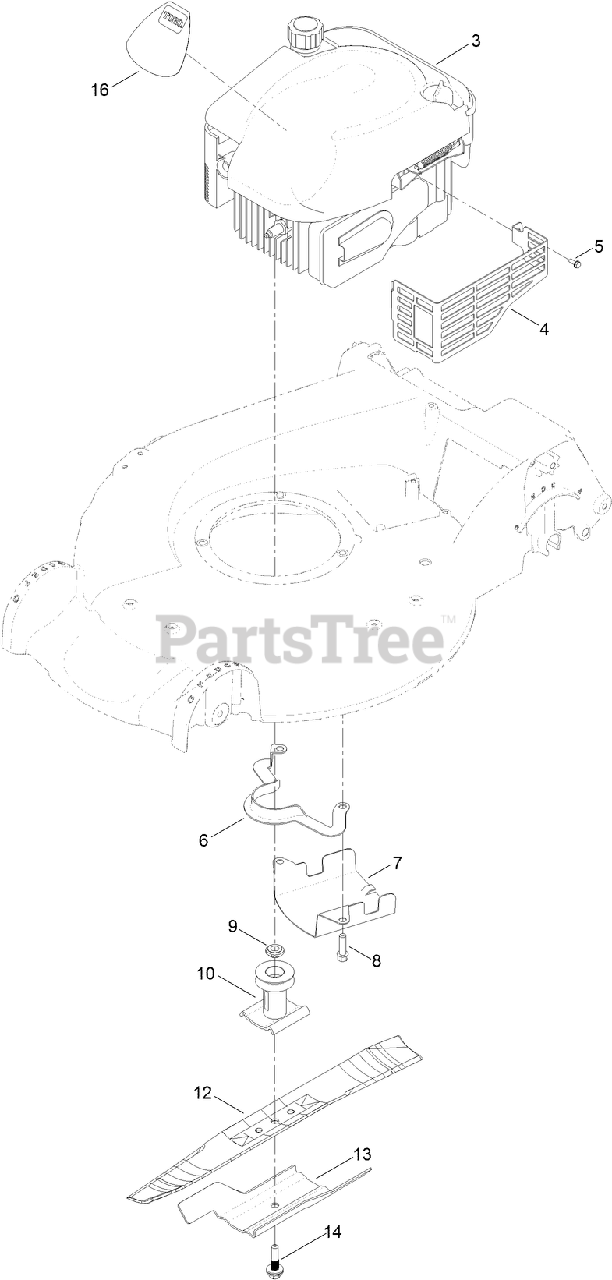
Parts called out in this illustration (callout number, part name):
4	SHIELD-MUFFLER
5	SCREW-TAPTITE
6	GUIDE-BELT
7	SHIELD-GRASS
8	SCREW-TAPTITE
9	SPACER-DRIVER
10	DRIVER-BLADE
13	ACCELERATOR-BLADE
14	BOLT-BLADE
16	DECAL-SHROUD
